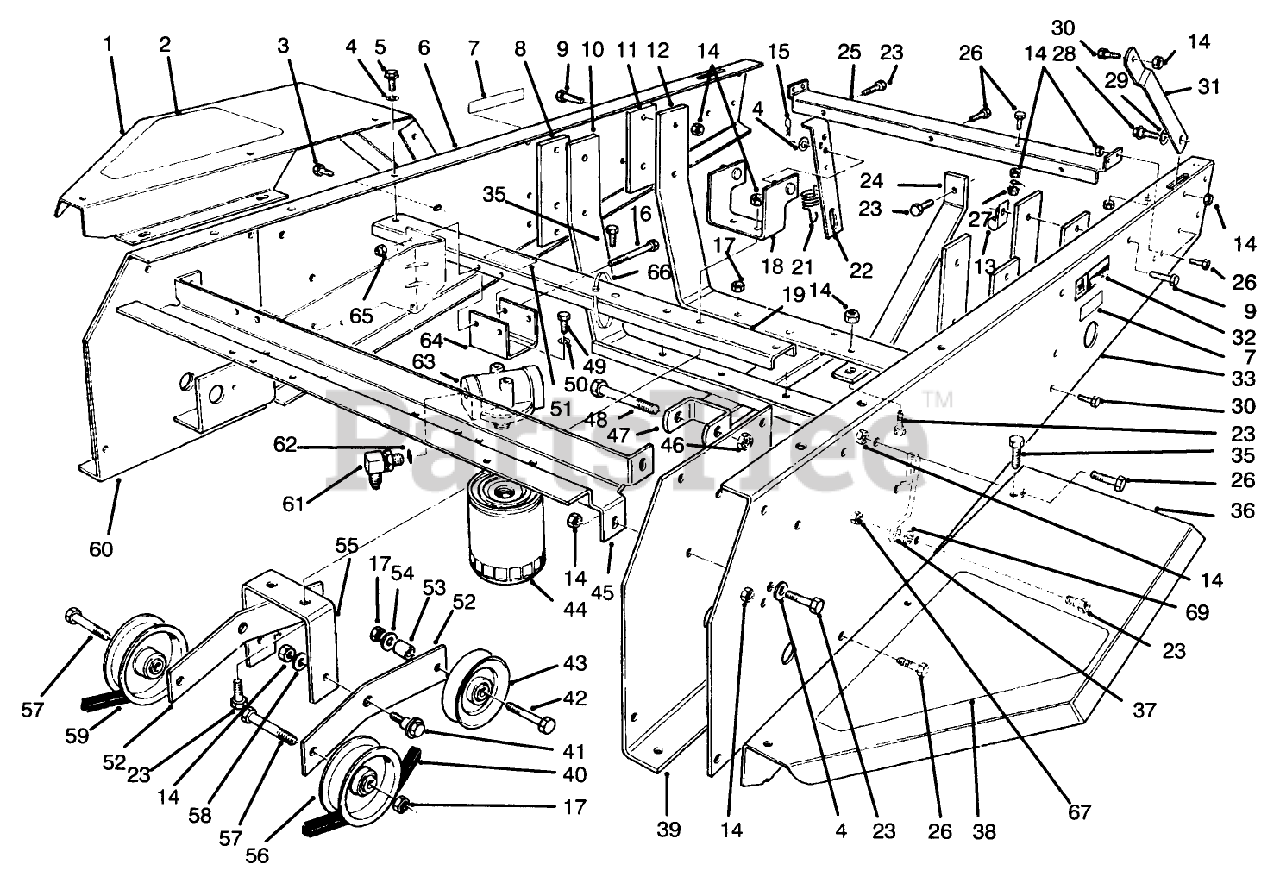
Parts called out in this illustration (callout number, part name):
1	Fender R.H
2	RH FENDER PAD
3	SCREW-HHF
4	WASHER-PLAIN
5	SCREW-HWHTF
6	Channel-Side R.H.
7	DECAL-WARNING
8	FRONT ENG PLATE
9	SCREW-HH
10	Mount-Engine
11	REAR ENG PLATE
12	Mount-Engine
14	NUT-LOCK, NI
15	PIN-COTTER
16	SCREW-HH
17	NUT-LOCK, NI
18	Anchor-Spring
19	MIDDLE CHANNEL WA B
20	SCREW-HH
21	IDLER SPRING
22	IDLER ANCHOR LINK
23	SCREW-HH
24	Bar-Tension
25	Support-Shield
26	SCREW-HH
27	NUT-KEPS
28	SCREW-SHOULDER
29	WASHER-SPRING
30	SCREW-HH
31	Stop-Hood Lower
32	DECAL-HOT
33	Channel-Side LH.
35	SCREW-HHFTF
36	Fender L.H.
37	BELT GUIDE
38	LH FENDER PAD
39	Axle Stand-LH.
40	V-BELT, JACKSHAFT
41	SCREW-SHOULDER
42	SCREW-HH
43	PULLEY
44	FILTER-OIL, TRANSMISSION
45	Channel-Front
46	NUT-LOCK
47	Mount-Cylinder
48	SCREW-HH
49	SCREW-HH
50	WASHER-LOCK
51	DECAL-OIL
52	IDLER LEVER
53	SPACER-WEIGHT
54	WASHER-FLAT
55	IDLER MT BRKT
56	PULLEY
57	SCREW-HH
58	WASHER
59	V-BELT, TRACTION
60	Axle Stand R.H.
61	FITTING-ELBOW, 90
62	O-RING
63	FILTER HD ASM
64	BRACKET - FILTER HEAD
65	NUT-LOCK, NI
66	TIE-CABLE
67	NUT-HF
69	WASHER-LOCK
